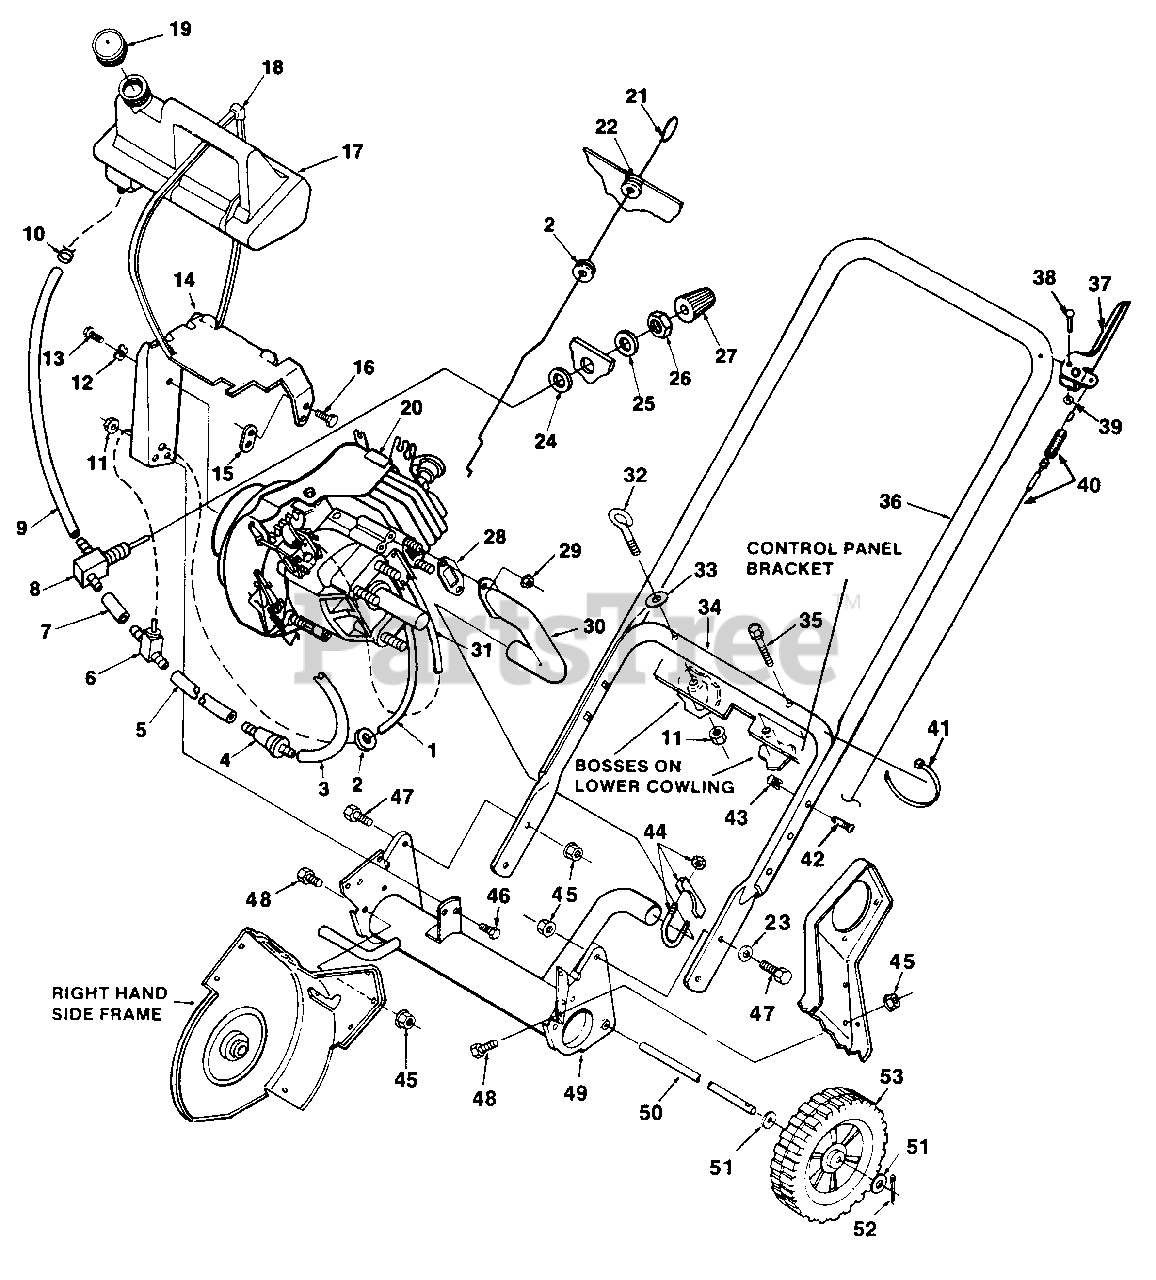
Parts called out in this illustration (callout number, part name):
1	FUEL LINE 17"
3	FUEL LINE- (cut to 8")
4	FILTER-Fuel
5	FUEL LINE (13 1/2")
6	FITTING-Fuel
7	FUEL LINE (cut to 1 1/2")
9	FUEL LINE (cut to 7 1/4)
11	NUT-Flange 1/4-20
12	WASHER-Shakeproof
13	BOLT- 1/4-20 x 3/8
14	BRACKET-Fuel tank
16	SCREW-10-24 x 3/4
17	FUEL TANK
18	STRAP-Tie
20	SHORT BLOCK
21	ROD-Choke
23	WASHER
24	WASHER-Flat
25	WASHER-Lock 7/16
26	NUT-R.H. 7/16-20
27	KNOB-Shut off
28	GASKET-Manifold
29	NUT-10-32
30	MANIFOLD-Exhaust
31	FUEL LINE (cut to 10 1/4")
33	WASHER
34	HANDLE-Lower
36	HANDLE-Upper
37	LEVER-Operating
40	CABLE & SPRING
41	TIE-Cable
43	RETAINER-Nut
44	CLAMP-Muffler
45	NUT-Flange 5/16-18
46	SCREW-1/4-20 x 1/2
47	SCREW-5/16-18 x 3/4
48	SCREW-Cap
50	AXLE-Shaft
51	WASHER
52	PIN-Cotter
53	WHEEL & TIRE
